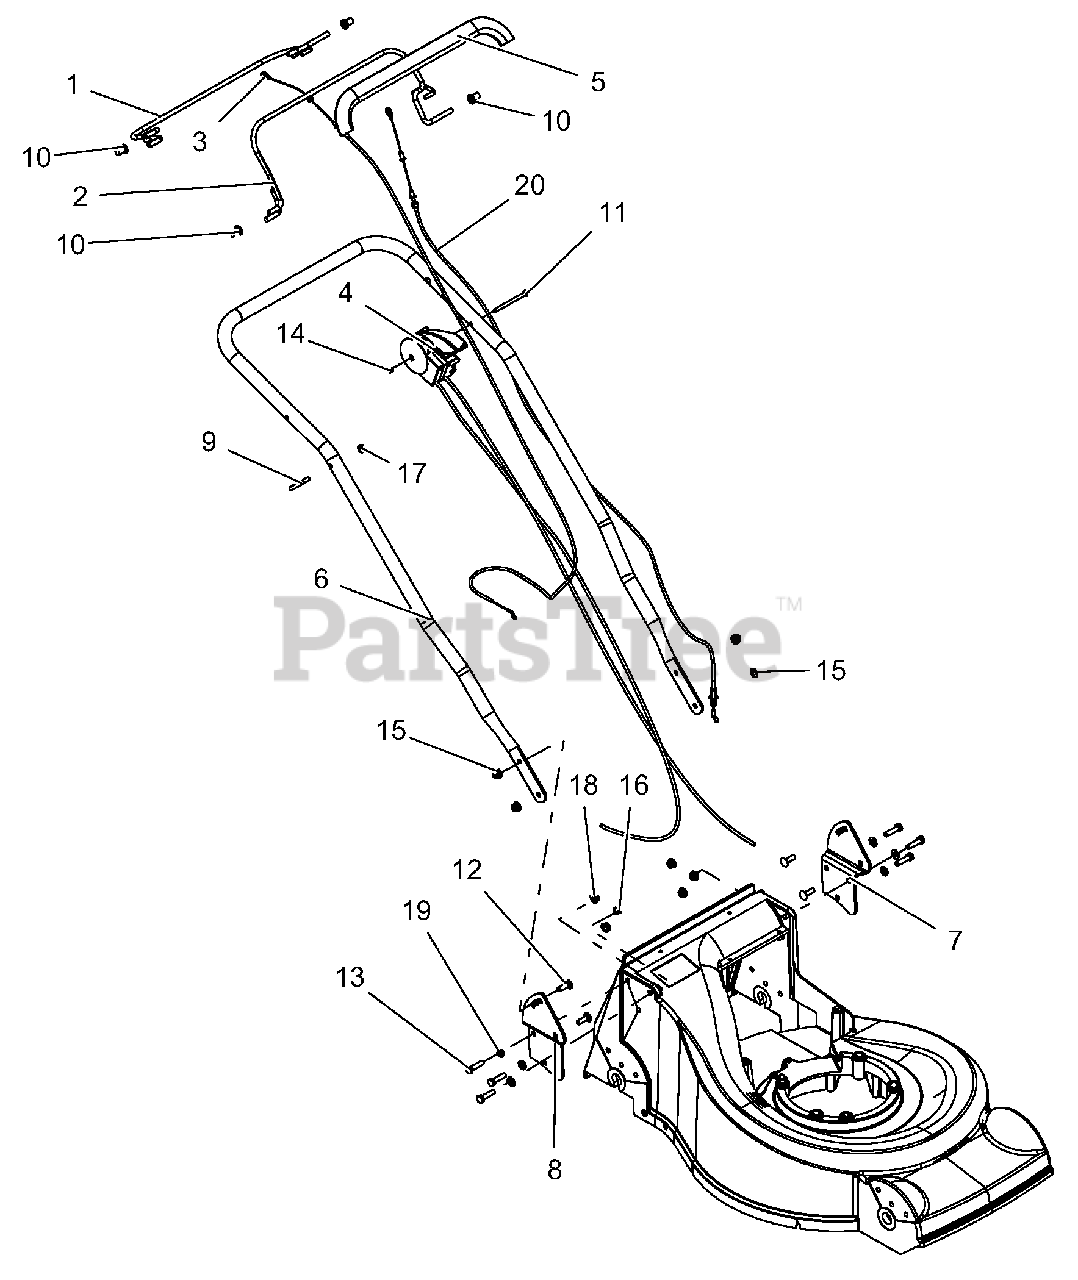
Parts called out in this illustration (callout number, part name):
1	OPC, LEVER
2	OPC, LEVER
3	CLUTCH, CONTROL ASSEMBLY
4	CONTROL, ASM SP SELECT & THROTTLE BBC
5	COVER, LEVER
6	HANDLEBAR, BENT
7	BRKT, HANDLEBAR -LEFT
8	BRKT, HANDLEBAR -RIGHT
9	HOLDER, RECOIL ROPE (BLACK)
10	BSHG, LEVER
11	SCR, MACHINE M6-1X80 PANHD
12	BLT-RDHDSQSHNK .31-18X1.00 G5 Y
13	BLT-HEX .31-18X1.25 GR5 YWZC
14	NUT-LK-NYL M6-1 YWZC
15	NUT-LK-NYL-FLG .31-18 YWZC
16	NUT-HEX .31-18 YWZC
17	NUT, LK-TOP-FLG .25-20 YWZC
18	NUT, LK-TOP-FLG .312-18 YWZC
19	WSHR-FL-STL.344X.688X.065YWZC
20	CABLE, OPC
